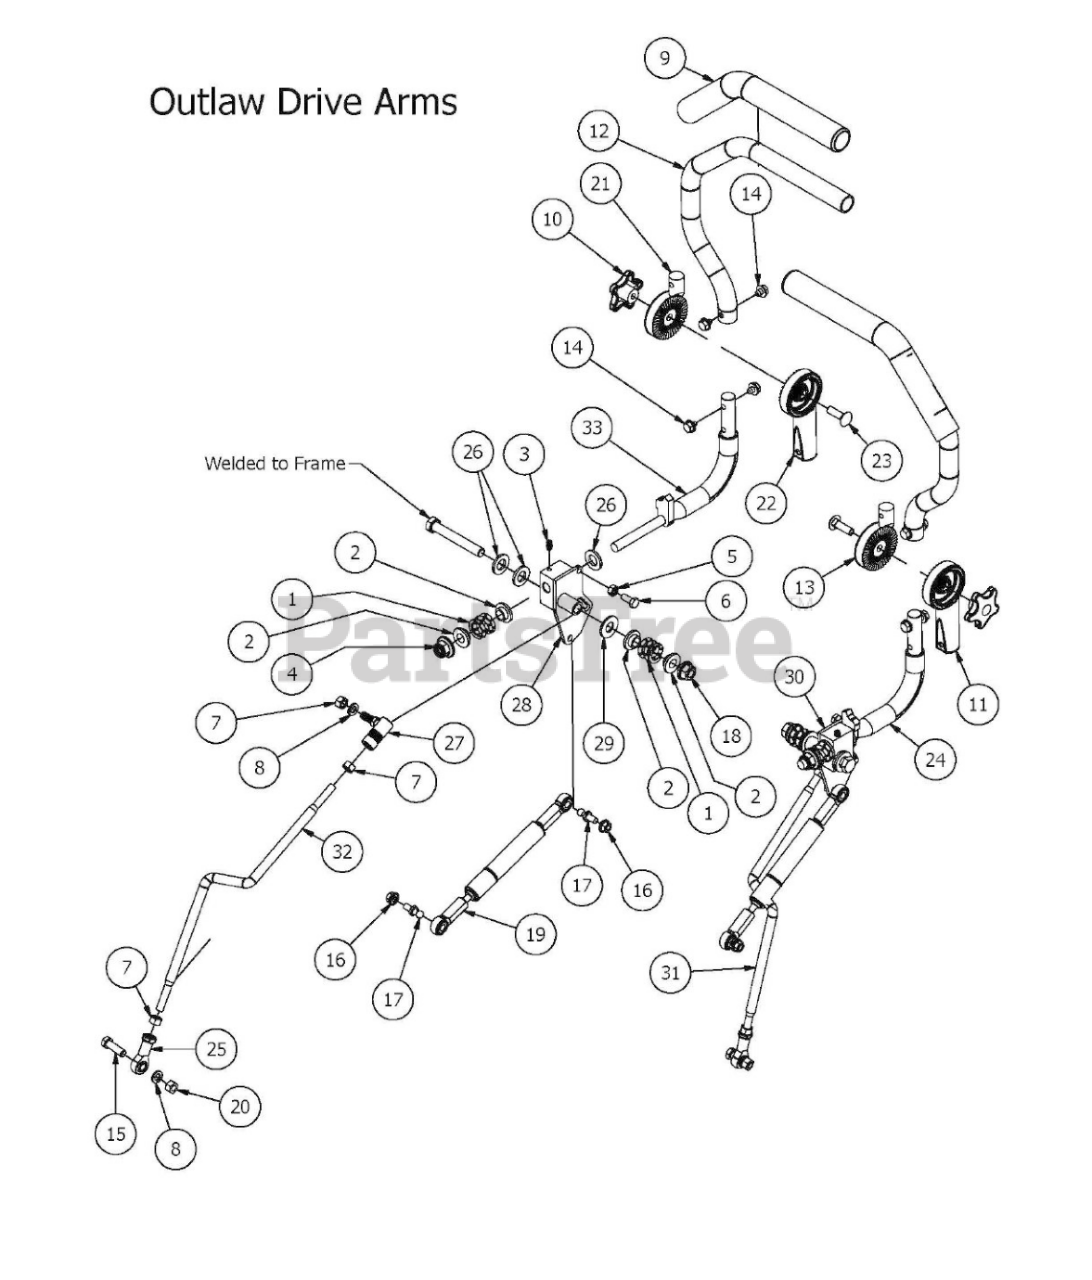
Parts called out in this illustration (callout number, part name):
1	Drive Lever Spring
2	.515 ID Nylon Shoulder Washer
3	1/4" Press in Grease Fitting
4	1/2-13 Nylon Flange Nut
6	5/16" x 3/4" Hex Bolt
7	3/8" Fine Threaded Jam Nut
8	3/8" Lock Washer
9	Black Steering Grip
10	Black Knob for Adjustable Steering Arm
11	Lower Adjuster -Steering Arm- Right
12	Upper Tube-Adjustable Steering
13	Upper Adjust Steering Arm- Right
14	5/16-18 1/2 HWH Bolt-Steering
15	3/8" x 1 1/4" Hex Bolt
16	5/16" Flange Nut
17	10mm Damper Ball Stud-Steering
18	1/2-13 Hex Flange (GR.G) ZC
19	Steering Damper
20	3/8-16 Hex Nuts Zinc
21	Upper adjuster-Steering Arm- Left
22	Lower Adjuster - Steering Arm- Left
23	3/8" x 1 1/4" Carriage Bolt
24	Steering Arm Elbow - Right
25	Spherical Rod End - Outlaw
26	.630 ID Plastic Washer
27	Quick Release Ball Joint
28	2017 Drive Lever Housing - Left
29	1/2" Washer (Grade 8)
30	2017 Drive Lever Housing - Right
31	2015 Outlaw Push Rod - Right
32	2015 Outlaw Push Rod - Left
33	Steering Arm Elbow - Left
